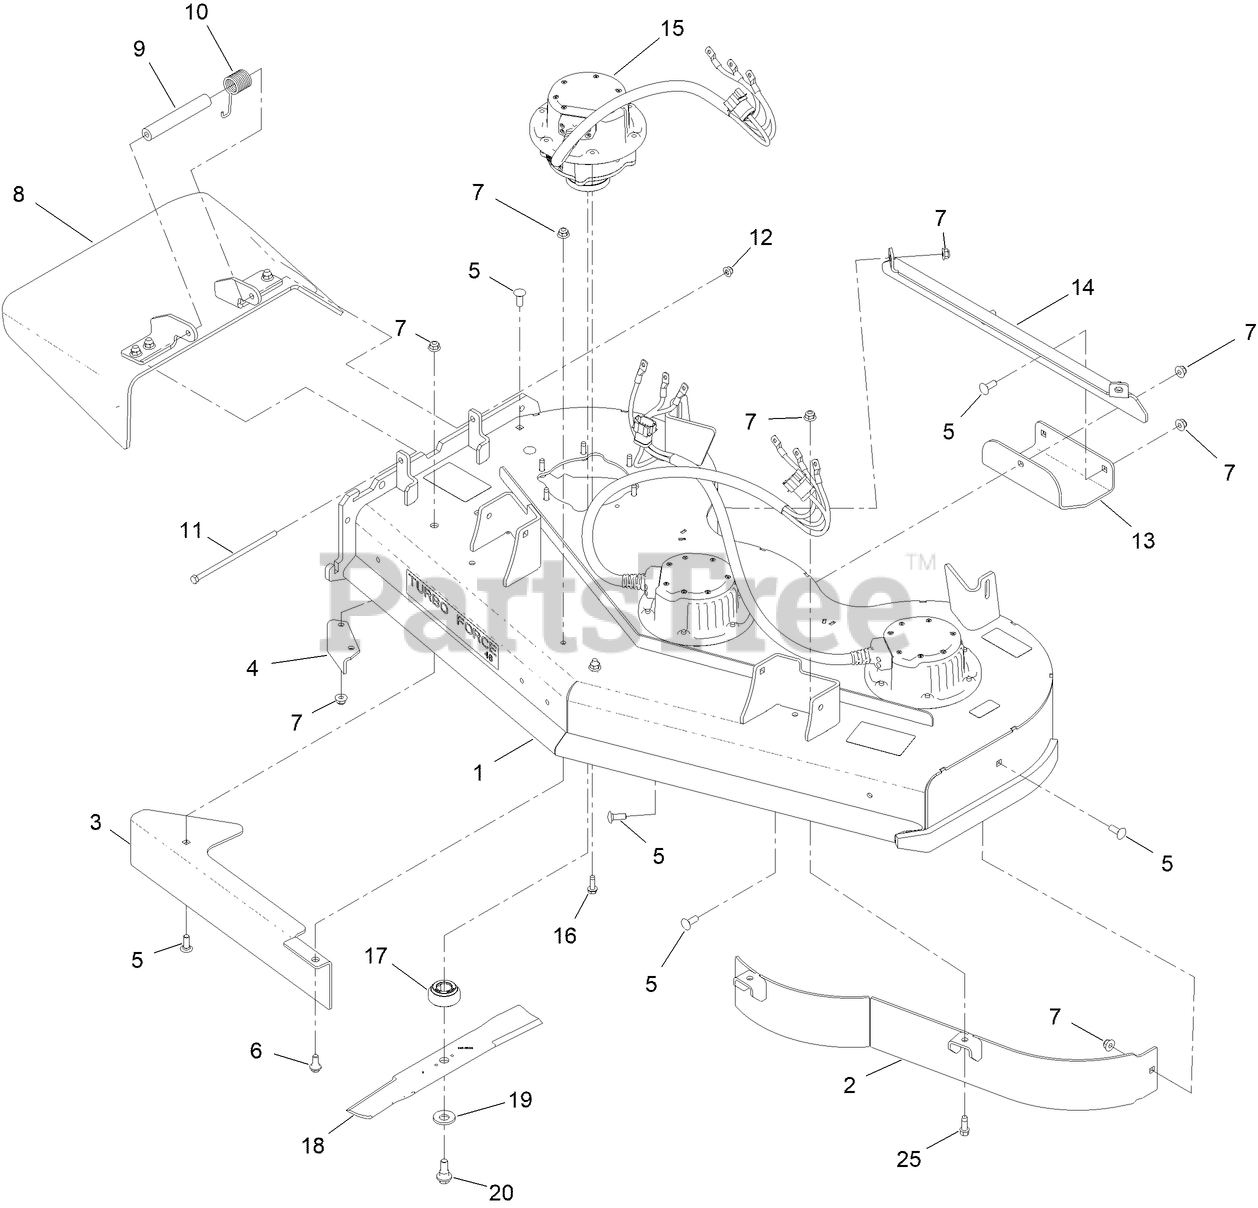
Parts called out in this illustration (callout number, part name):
1	DECK ASM-48IN
1	SCREW-CARR
2	BAFFLE ASM, 48IN [RED]
2	DEFLECTOR
3	PLATE-BAFFLE, FORMED [RED]
3	STRAP-DISCHARGE
4	BAFFLE-DISCHARGE
4	DEFLECTOR-DECK, RUBBER
5	SCREW-CARR
5	PLATE-HINGE, REAR
6	BOLT-SHOULDER
6	PLATE-HINGE, FRONT
7	NUT-HF, NI
8	RUBBER DEFLECTOR ASM
9	SPACER
10	SPRING-TORSION
11	SCREW-HH
12	NUT-HF, NI
14	BRACKET-SKID
15	MOTOR/GEN-48V,
16	SCREW-THD ROLL, HWH
17	RETAINER-BLADE
18	BLADE-16.5IN, MED SAIL
19	WASHER-BELLEVILLE
20	SCREW-SHOULDER,HWH
